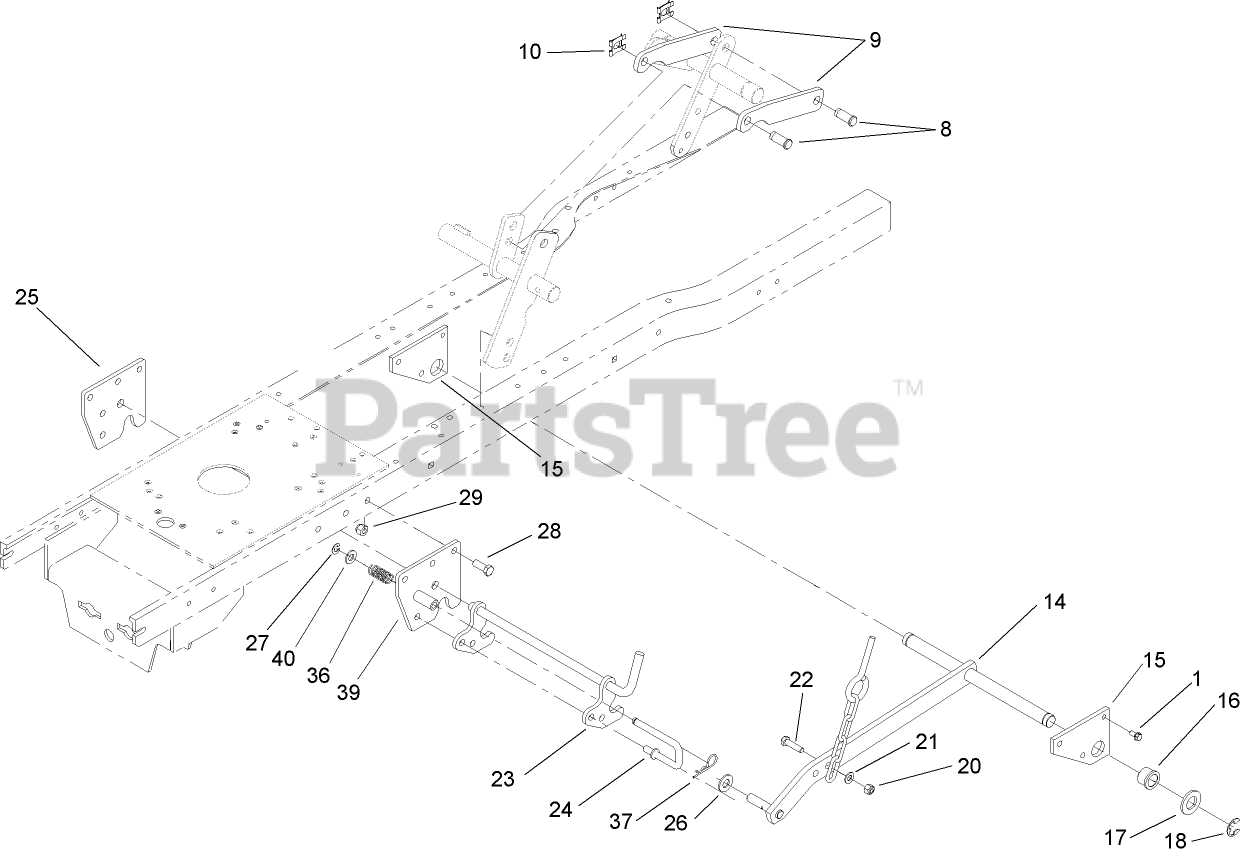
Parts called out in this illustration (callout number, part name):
1	SCREW-HWHTF
8	PIN-CLEVIS
9	STRAP-LINK, LIFT
10	CLIP-PIN
14	LIFT BAR ASM
15	PLATE-LIFT, REAR
16	BUSHING-FLANGE
17	WASHER-FLAT
18	E-RING
20	NUT-LOCK, NI
21	WASHER-PLAIN
22	SCREW-HH
23	MIDHITCH LATCH ASM
24	ROD-CATCH
25	PLATE-HITCH
26	WASHER-FLAT
27	RING-RETAINING
28	SCREW-HH
29	NUT-LOCK, NI
36	SPRING-COMPRESSION
37	PIN-HAIR
39	MIDHITCH ASM
40	WASHER-FLAT
